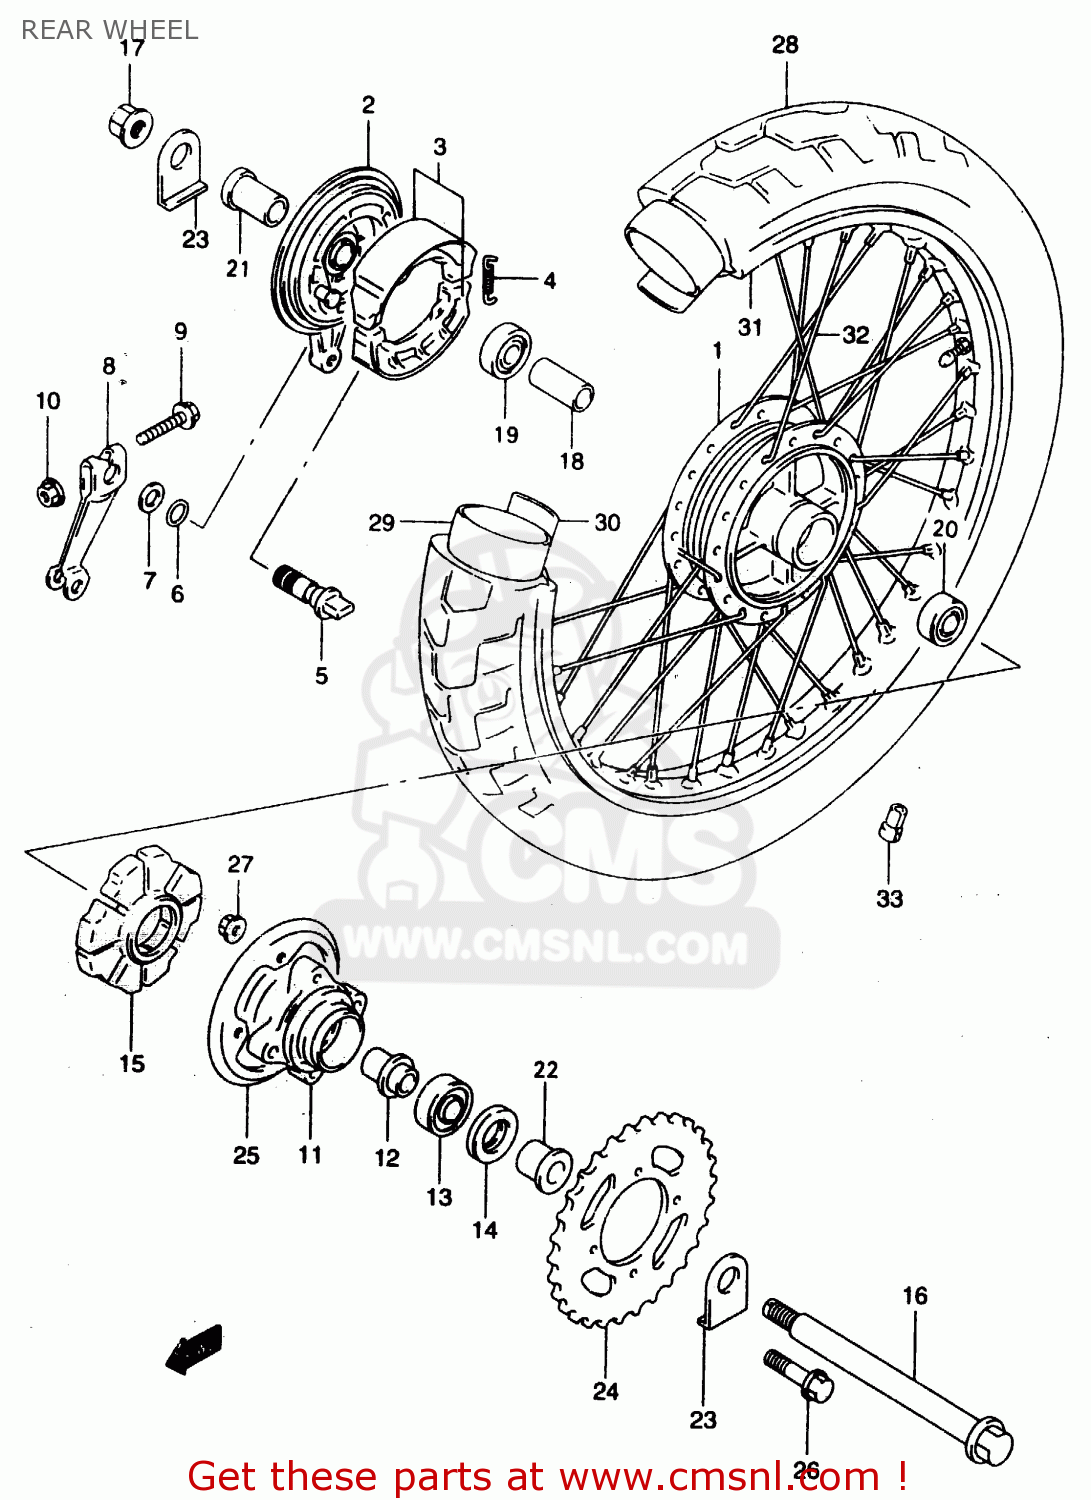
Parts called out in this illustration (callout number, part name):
1	HUB,RR WHEEL
2	PANEL,RR BRAKE ANCHOR
3	SHOE SET,BRAKE (NAS)
4	SPRING(L:34)
5	CAM,BRAKE
6	O RING(D:2.5,ID:13.8)
7	WASHER(14.5X22X1.6)
8	LEVER,RR BRAKE CAM
9	BOLT
10	NUT
11	DRUM,RR SPROCKET MOUNTING
12	RETAINER,RR SPROCKET DRUM
13	BEARING(20X47X14)
14	SEAL,OIL(28X47X7)
15	ABSORBER ASSY,HUB SHOCK
16	AXLE,RR
17	NUT
18	SPACER(15.3X21.7X63)
19	BEARING
20	BEARING
21	SPACER,RR AXLE,R
22	SPACER,RR AXLE,L
23	WASHER,CHAIN ADJUSTER GUIDE
24	SPROCKET,RR(NT:45-428)
25	GUIDE,RR SPROCKET CHAIN
26	BOLT(10X40)
27	NUT
28	TIRE,RR(130/90-15)
29	TUBE ASSY,WHEEL INNER
30	PROTECTOR,WHL INR TUBE
31	RIM,RR WHEEL(15XMT3.00)
32	SPOKE SET,RR WHEEL
33	BALANCER,WHEEL (B)
